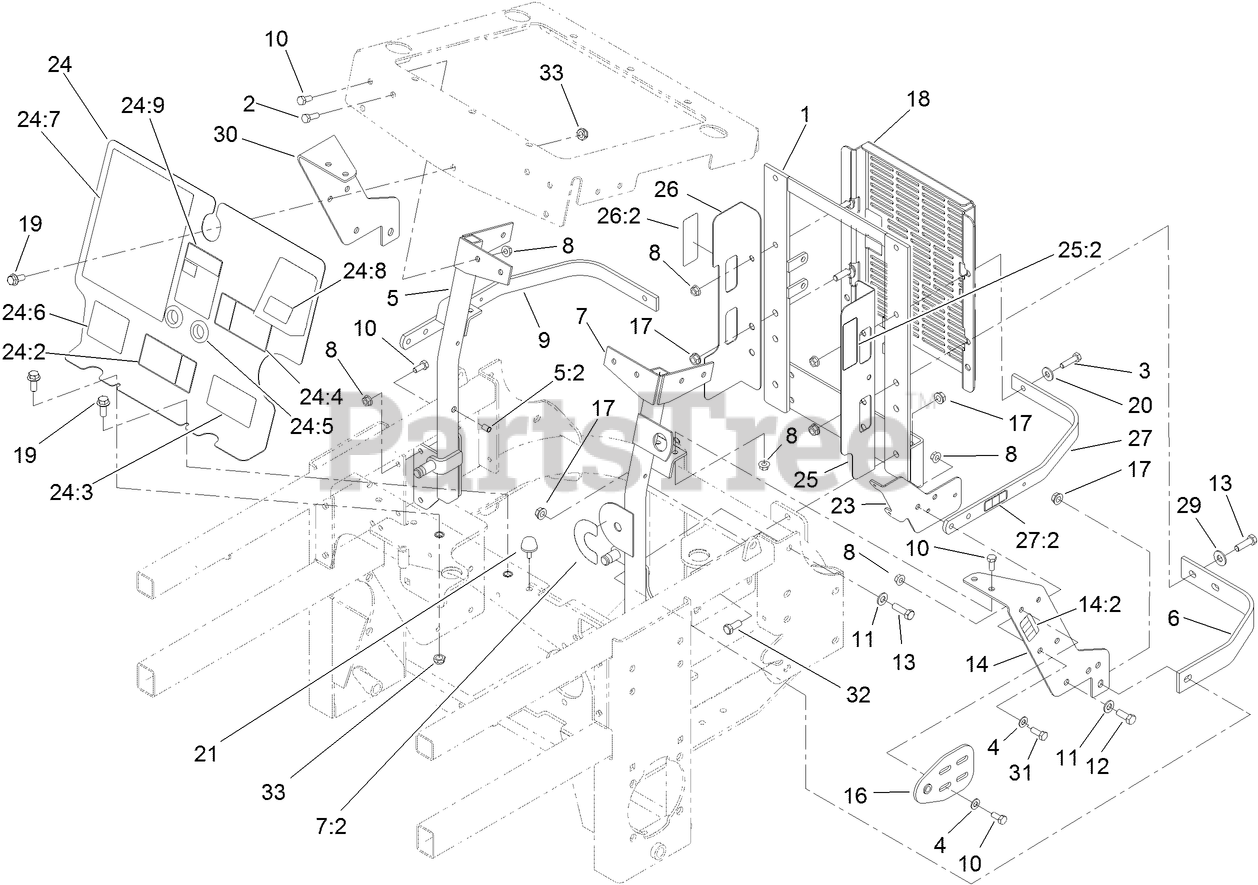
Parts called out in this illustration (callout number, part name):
1	SUPPORT-RADIATOR, REAR
2	SCREW-HH
3	SCREW-HH
4	WASHER-PLAIN
5	RH RADIATOR BRACE ASM
5:2	INSERT-THREADED
6	STRAP-GUARD
7	LH RADIATOR BRACE ASM
7:2	DECAL-VALVE, FUEL
8	NUT-HF
10	SCREW-HH
11	WASHER-FLAT
12	SCREW-HH
13	SCREW-HH
14	LH SUPPORT BRACKET ASM
14:2	DECAL-FUSE
16	PLATE-PIVOT, HOOD
17	NUT-HHF, WHIZ
18	SHIELD-COOLER
19	SCREW-HHF
20	WASHER-FLAT
21	BUMPER-RUBBER
23	BRACKET-RELAY, FUSE
24	FRONT SHIELD ASM
24:2	DECAL-DANGER, ROTATING DEVICES
24:3	DECAL-ROUTING, HYDRO BELT
24:4	DECAL- WARNING, BUZZER
24:5	GROMMET-RUBBER
24:6	DECAL-ROUTING, CLUTCH BELT
24:7	DECAL-CHECK SERVICE
24:8	DECAL-CAUTION
24:9	DECAL-COOLANT
25	GUARD-FAN, LH (CE)
25:2	DECAL-DANGER
26	GUARD-FAN, RH (CE)
26:2	DECAL-DANGER
27	TOP STRAP ASM
27:2	DECAL-RELAY
29	WASHER-FLAT
30	BRACKET-SUPPORT, RH
31	SCREW-HH
32	SCREW-HH
33	NUT-LOCK, NI
